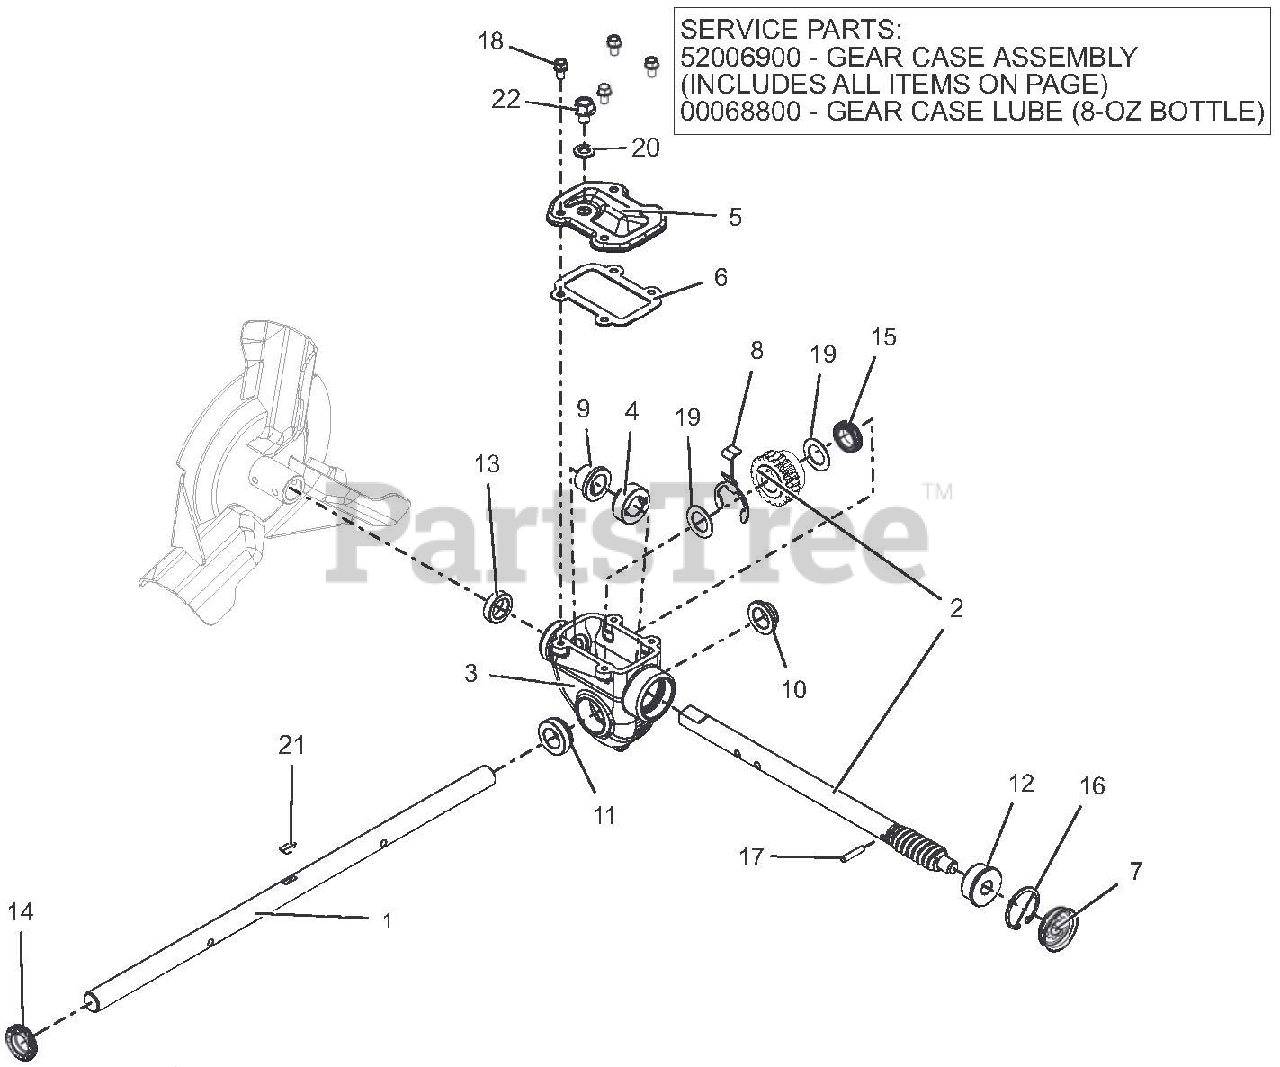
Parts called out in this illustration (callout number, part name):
1	SHAFT, RAKE - 20" (.750 DIA)
2	SHAFT AND WORM GEAR ASSEMBLY
3	GEARCASE, COMPACT MACHINED
4	THRUST COLLAR, .75" ID SLIPFIT
5	COVER, TOP - COMPACT
6	GASKET, TOP - COMPACT GEARCASE
7	COVER, GEAR CASE 1.50"
8	BUSHING RETAINER, COMPACT
9	BSHG-FLG .755X.878X.75X1.25
10	BSHG-FLG .755X.878X.424X1.25
11	BSHG-FLG COMPACT, RIGHT
12	BSHG-FLG .503X1.303X.62X1.465
13	SEAL-OIL .748X1.125X.312 TB2-H
14	SEAL-OIL .748X1.300X.250 TBC29
15	SEAL-OIL .748X1.125X.312 TBC29
16	RG-RTNG-INT 1.500X.050
17	PIN-STR .188X1.00 6150
18	BOLT, SEMS .25-20X.50 GR5 YWZC
19	WSHR-FL-STL .760X1.225X.032 YZ
20	WSHR-BND-SEAL .38X.75X.11 GALV
21	KEY-WDRF .19X.63 HRD #61
22	@SCR-ROLOK .38-16X.50 HWH YWZC
23	GEAR CASE, 20" IRON SM TOP-LD
